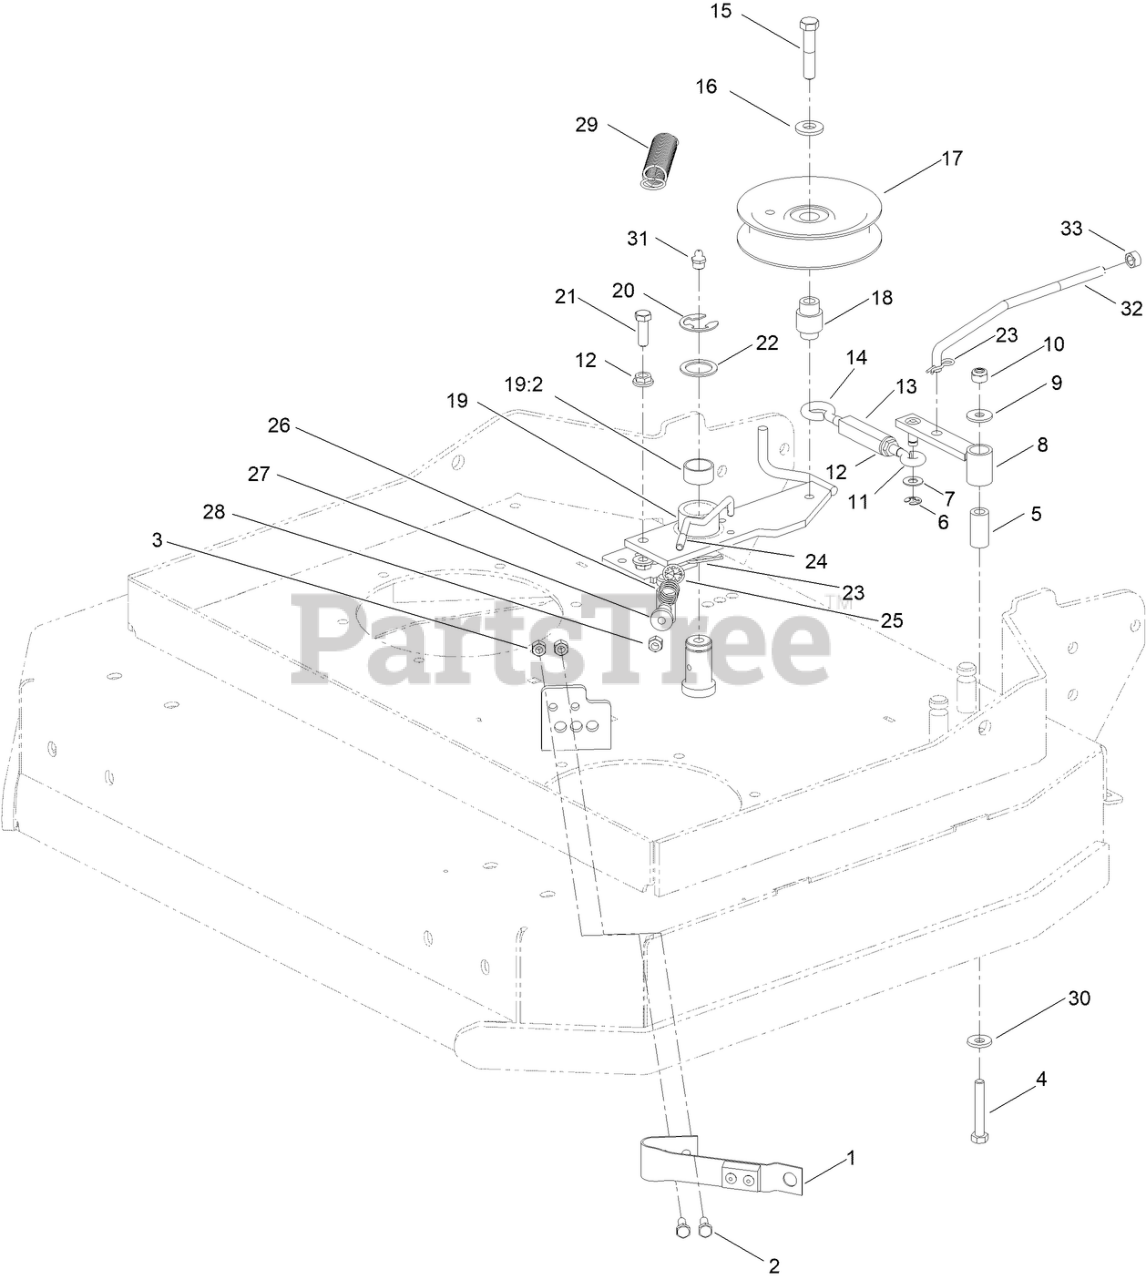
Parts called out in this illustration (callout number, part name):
1	PAD AND SPRING ASM
2	SCREW-HH
3	NUT-LOCK, NI
4	SCREW-HH
5	TUBE-PIVOT
6	RING-RETAINING, EXT
7	WASHER
8	ARM-ASSIST, 32/36
9	WASHER
10	NUT-NYLOC
11	EYEBOLT-THREAD, RH
12	NUT-HF
13	BODY-TURNBUCKLE
14	EYEBOLT-THREAD, LH
15	SCREW-HH
16	WASHER-BELLEVILLE
17	PULLEY-IDLER, FLAT
18	BUSHING-ENGAGEMENT
19	IDLER ARM ASM
19:2	SLEEVE-BEARING
20	RING-RETAINING, EXT
21	SCREW-HH
22	WASHER-SPINDLE
23	PIN-COTTER
24	ROD-BRAKE
25	RING-PUSH ON
26	SPRING-COMPRESSION
27	SPACER-FLANGED
28	NUT-LOCK, NI
29	SPRING-EXTENSION
30	WASHER-SPRING
31	FITTING-STRAIGHT
32	ROD-LINKAGE, DRIVE
